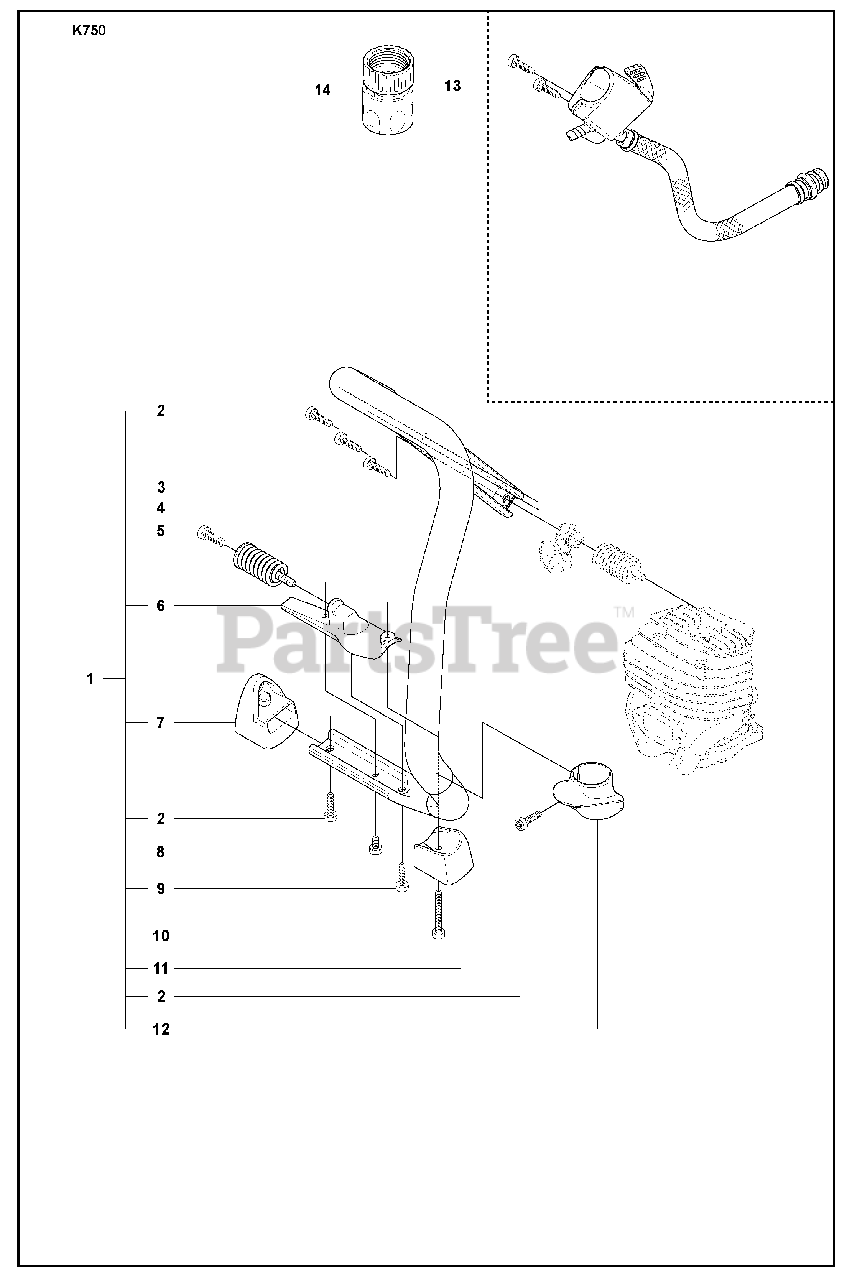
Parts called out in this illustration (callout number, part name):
1	HANDLE
3	FRONT HANDLE
4	AV-ELEMENT
6	SPRING RETAINER
7	GROUND SUPPORT
11	GROUND SUPPORT
13	HOSE
14	COUPLER
